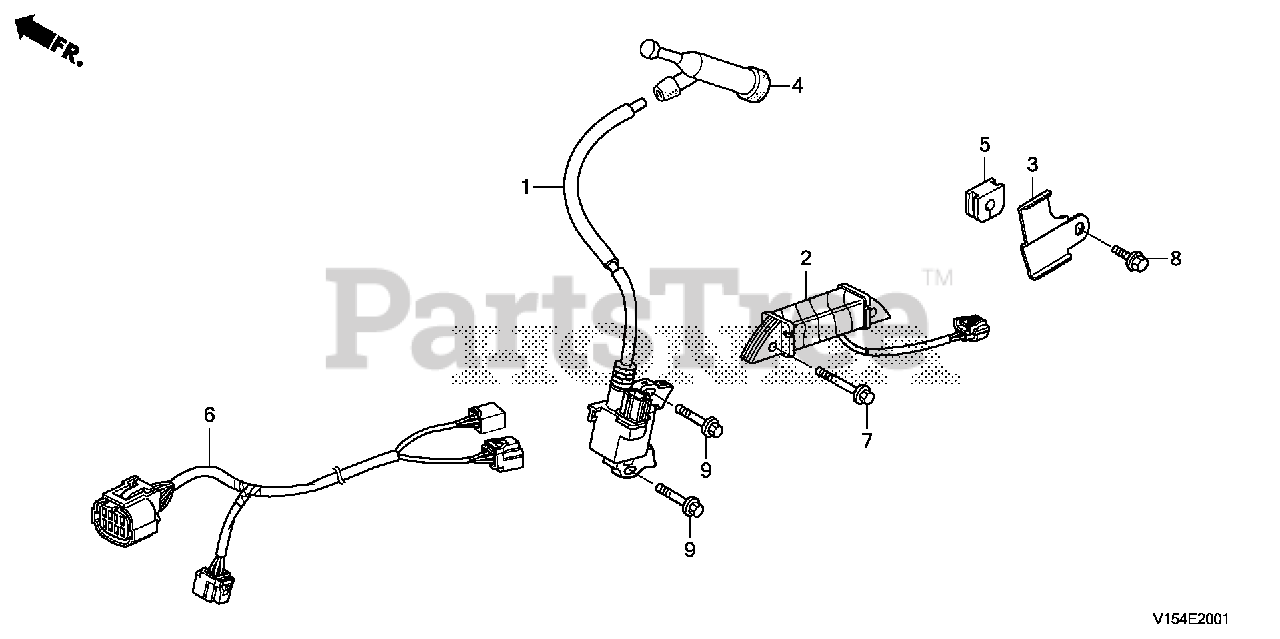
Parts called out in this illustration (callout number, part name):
1	COIL ASSY., IGNITION
2	COIL ASSY., POWER
3	BRACKET B, HARNESS
4	CAP ASSY., NOISE SUPPRESSOR (NGK Y-EZD)
5	GROMMET, WIRE
6	WIRE HARNESS ASSY., ENGINE
7	BOLT, FLANGE (6X40) (CT200)
8	BOLT, FLANGE (6X12) (CT200)
9	BOLT, FLANGE (6X28) (CT200)
